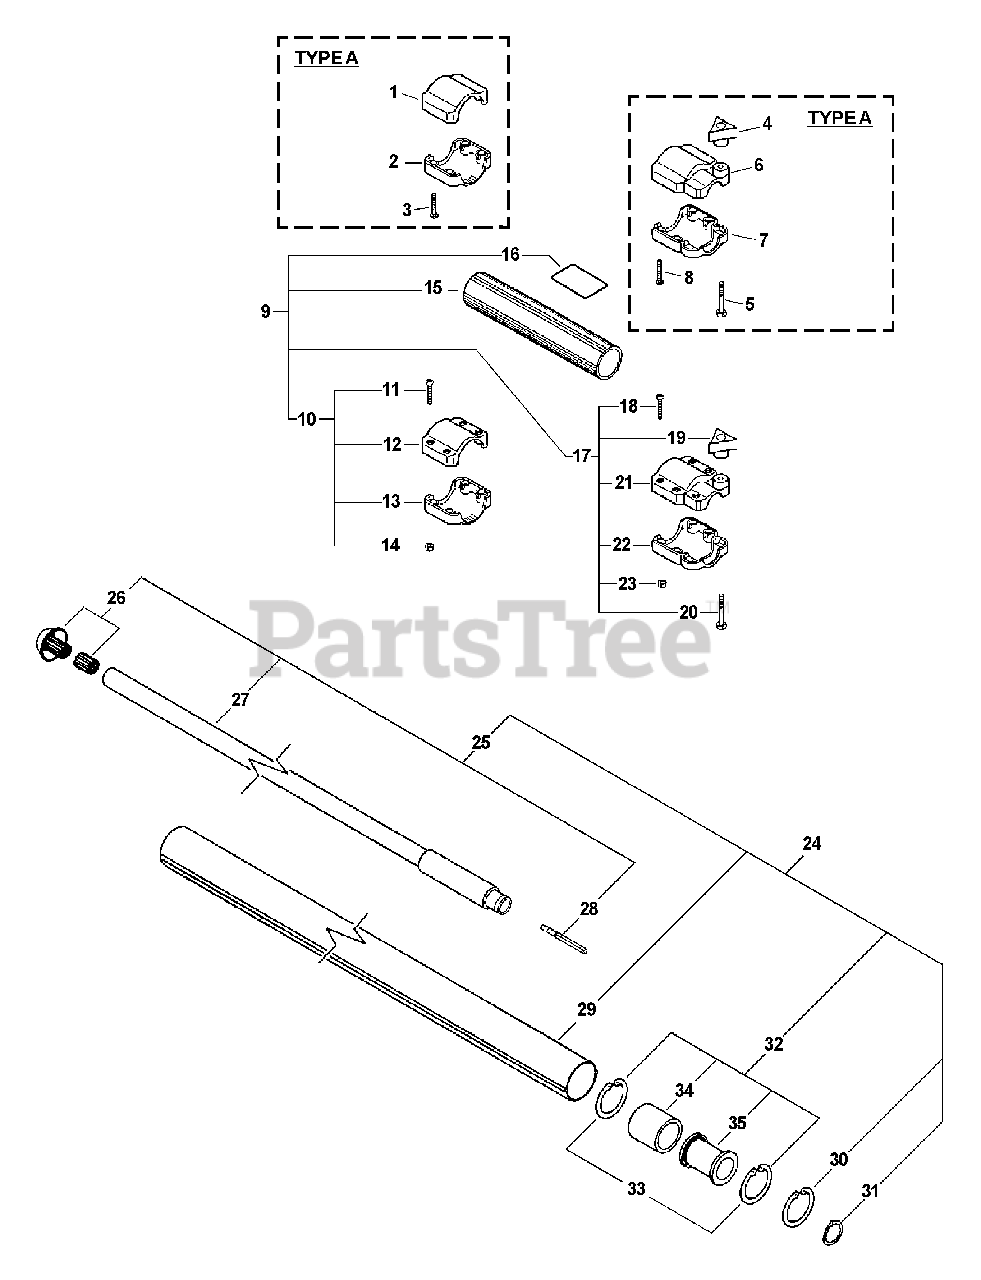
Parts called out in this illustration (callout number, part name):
3	SCREW, TORX 10-24 UNC 1-1/4
4	THUMBSCREW
6	COLLAR, MAIN PIPE - UPPER
7	COLLAR, MAIN PIPE - LOWER
8	SCREW, TORX 10-24 UNC 1-1/4
9	MAIN PIPE ASSY
10	FRONT COVER
11	SCREW, TORX 10-24 UNC 1-1/4
12	COLLAR, MAIN PIPE - UPPER
13	COLLAR, MAIN PIPE - LOWER
14	NUT, LOCK 10-24 UNC
15	PIPE, MAIN
16	LABEL - CAUTION
17	CLAMP ASSY
18	SCREW, TORX 10-24 UNC 1-1/4
19	THUMBSCREW
21	COLLAR, UPPER
22	COLLAR, LOWER
23	NUT, LOCK 10-24 UNC
24	MAIN PIPE ASSY
25	DRIVESHAFT ASSY - UPPER
26	ADAPTER, UPPER DRIVE SHAFT
27	DRIVESHAFT
28	CONNECTOR, DRIVE SHAFT
29	MAIN PIPE ASSY
30	RING, SNAP
31	RING, RETAINING
32	DRIVESHAFT GUIDE ASSY
33	RING, SNAP
34	PAD, FOAM
35	GUIDE, DRIVESHAFT
